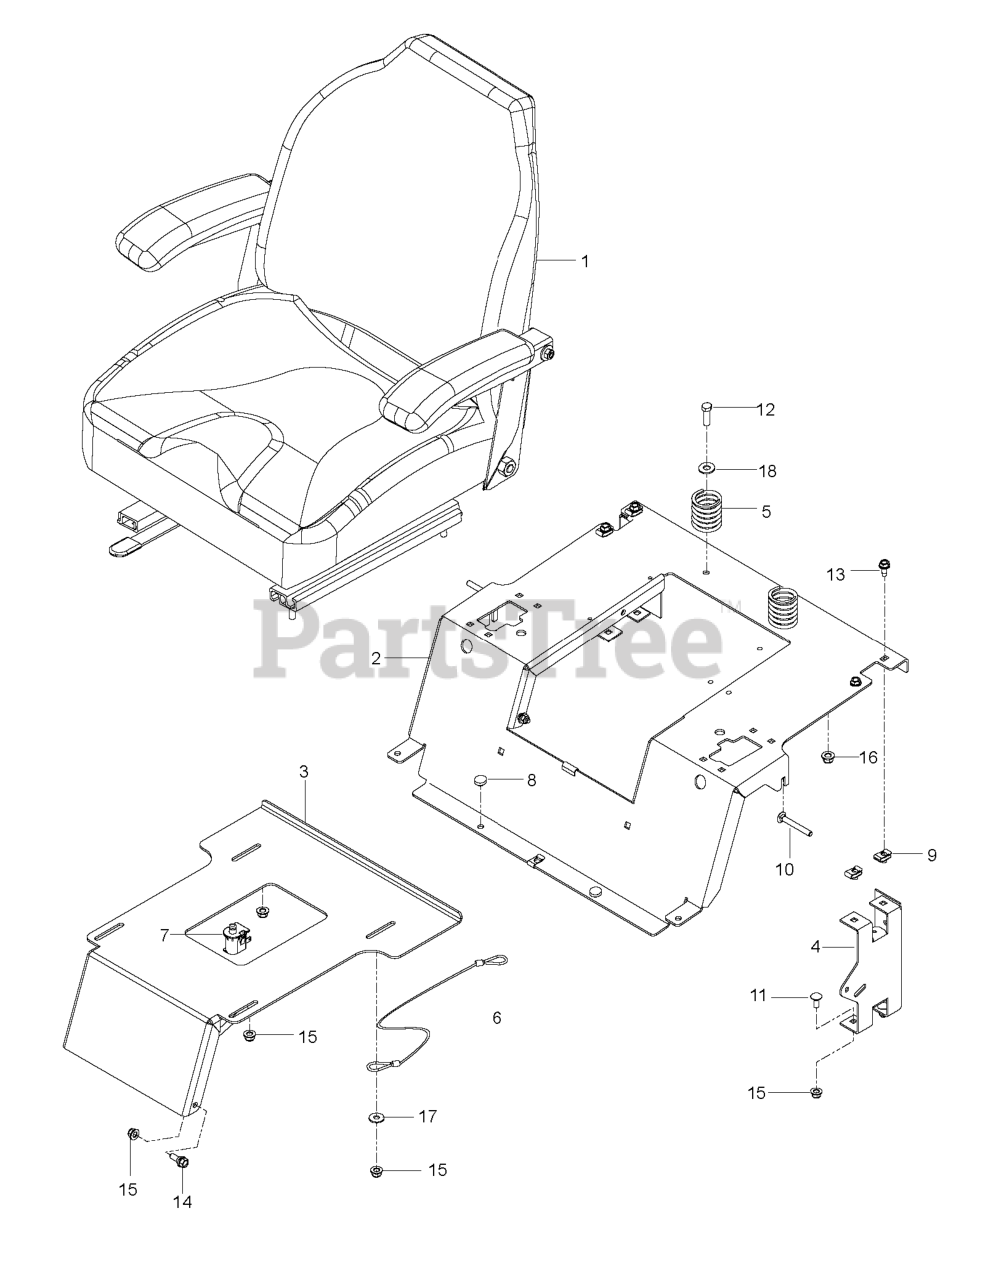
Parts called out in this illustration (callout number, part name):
1	SEAT.907.VINYL.HUSQVARNA
2	SUPPORT SEAT FLAT ORANGE
3	PAN, SEAT ORG
5	SPRING COMPRESSION
6	SEAT LANYARD
7	SEAT SWITCH
8	GROMMET, BUMPER
9	U-CLIP 5/16-18 NUT RETAINER
10	RHSNB 5/16-18 X 2-1/2 GR5 ZD
11	BOLT 5/16C X 3/4" CARRIAGE
12	HCS 3/8C X 1 1/4 GR5
13	SCREW.THDROL.5/16-18X3/4.TTY
14	SB 5/16-18 HEX HD GD5, BLK ZN
15	5/16-18 NYLOC FLANGE NUT
16	NUT 3/8-16 NYLOC
17	WASHER 5/16 FLAT
18	WASHER 3/8 SAE FLAT
